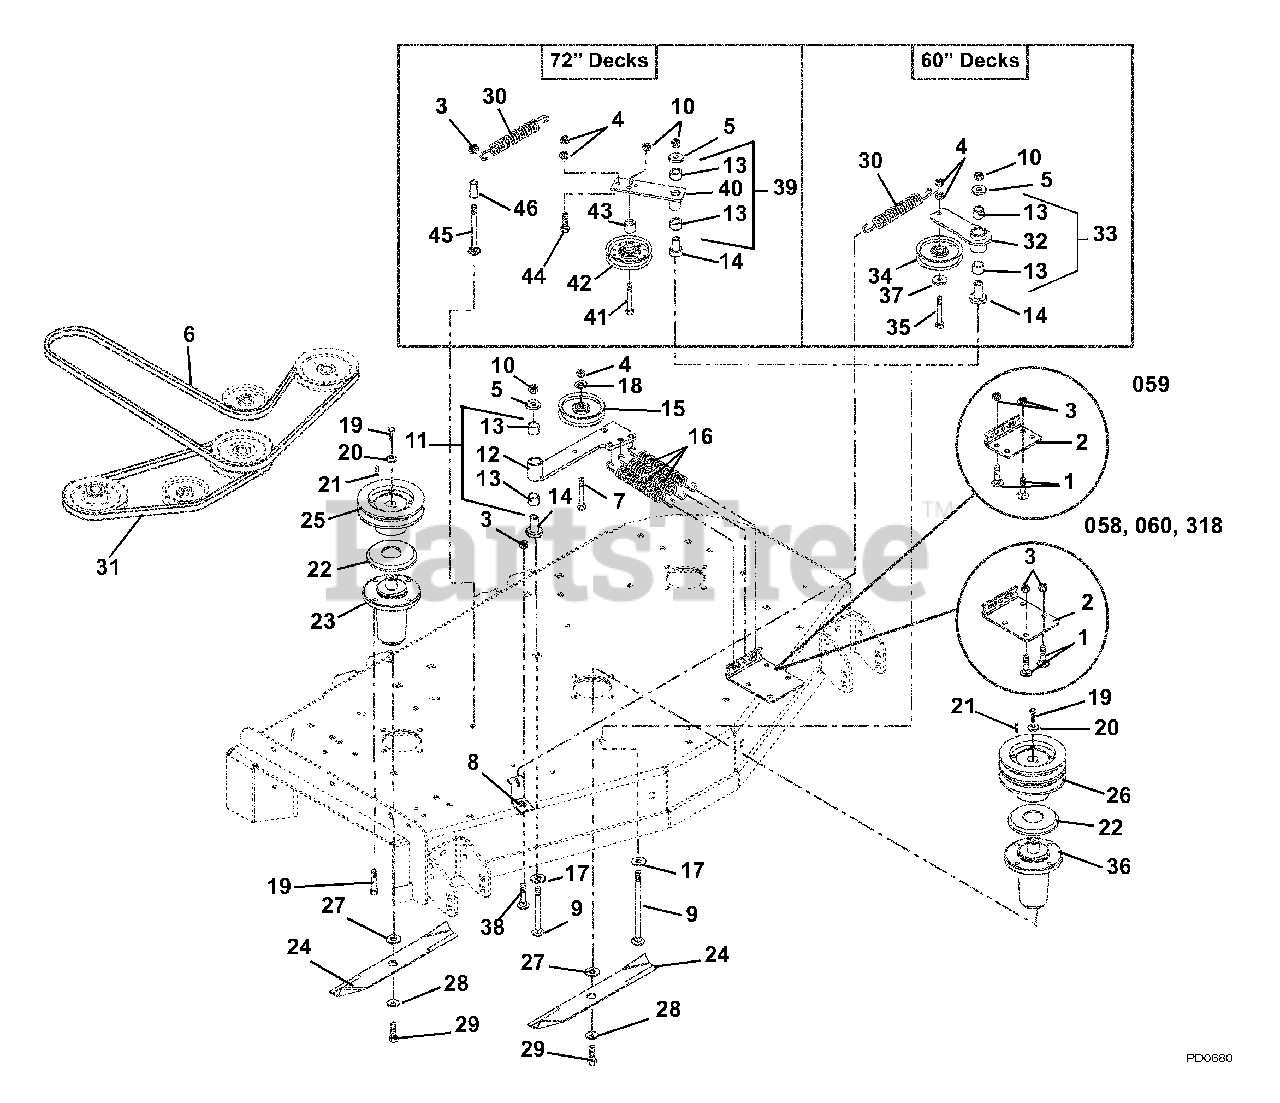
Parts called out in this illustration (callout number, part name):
1	Bolt, Round Head Square Neck .38-16 x .75 Grade 5
2	Bracket, Spring
2	Bracket, Short Spring
3	Nut, Locking Top Flange .38-16
4	Nut, Locking Center .38-16
5	Washer, Flat Steel .531 x 1.25 x .10
6	V-Belt, B-Section 54.06 x .625
6	V-Belt, B-Section 58.25 x .625
7	Bolt-Round Head Square Neck .38-16 x 2.75 Grade 5
8	Anchor, Spring
9	Bolt, Round Head Square Neck .50-13 x 3.50 Grade 5
10	Nut, Locking Top Flange .50-13
11	Assembly-Deck Idler Pivot Arm
12	Weldment, Deck Idler Pivot Arm
13	Bearing, 1.00 x 1.12 x .75
14	Bearing, Pedestal Powdered Metal
15	Idler, Flat 4.00 x .38 (2.32W)
16	Spring, Extension
17	Washer, Flat Steel .755 x 1.375 x .062
18	Washer, Flat Steel .375 x 1.125 x .065
19	Bolt, Hex .38-16 x 1.00 Grade 8
20	Washer, Flat Steel .406 x 1.50x .245
21	Key, Square .25 x .25 x 1.00
22	Slinger, Dust
23	Assembly, Maintenance Free Spindle
24	Blade 60" Mower CE
24	Blade, Mower 60" Mulch
24	Blade, Mower-72" (24.50" LG)
24	Blade, Mower
24	Blade, Mower 72" Mulch
25	Weldment, Spindle Sheave 6.00
25	Weldment, Spindle Sheave
26	Sheave, Double (6.25)
26	Sheave, Double (7.25)
27	Washer, Flat .64 x 1.81 x .25
28	Washer, Bellville .63 x 1.625 x .14
29	Bolt, Hex .62-18 x 1.75 Grade 8
30	Spring, Extension
31	V-Belt B-Section 23.94 x .625
31	V-Belt 5L-Section 49.97 x .672
32	Arm, Idler Pivot
33	Asm, Idler Pivot Arm
34	V-Idler, 4.00 x .38
35	Bolt, Hex .38-16 x 2.25 Grade 5
36	Spindle Assembly (Center)
37	Washer, Flat Steel .406 x .812 x .05
38	Bolt, Round Head Square Neck .38-16 x 1.00 Grade 5
39	Assembly, Idler Arm Guard Drive
40	Weldment, Idler Arm Ground Drive
41	Bolt, Hex .38-16 x 6.00 Grade 5
42	Idler, Flat Pulley 6.75 x .51
43	Spacer .513 x .748 x .62
44	Bolt, Hex .38-16 x 1.25 Grade 5
45	Bolt, Round Head Square Neck .38-16 x 2.75 Grade 5
46	Spacer .38 x .625 x 1.50
